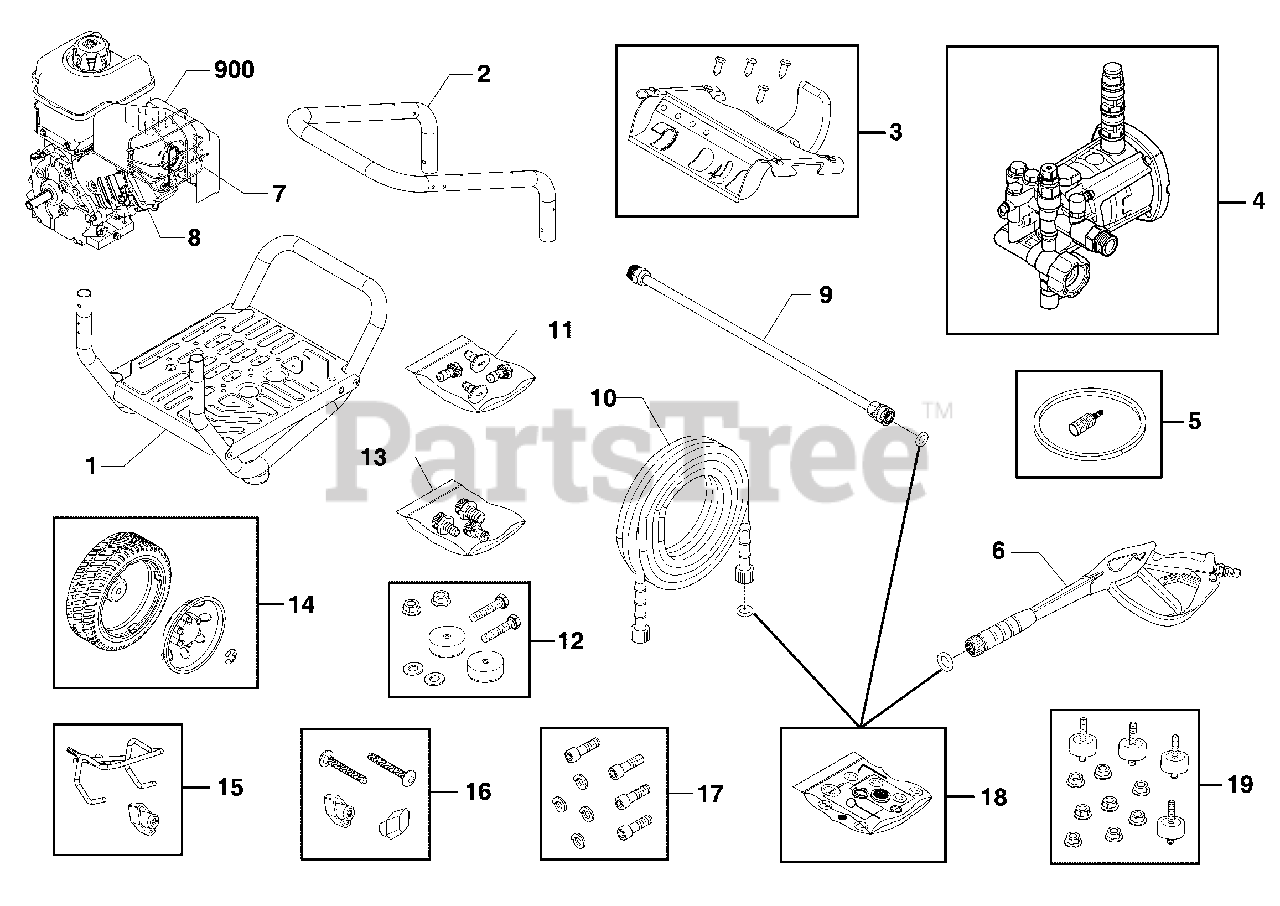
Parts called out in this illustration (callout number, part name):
4	PUMP
5	KIT, Chem Hose & Filter
7	Guard-Muffler
11	KIT-QC NOZZLES
12	KIT, Vibration Mount
13	KIT-GARDEN HOSE
15	KIT, Gun Holder, Weldment
16	KIT, Hardware, Handle
17	KIT, Hardware, Pump Mounting
18	KIT-O-RING MAINTENANCE
19	KIT, Vibration Mount
